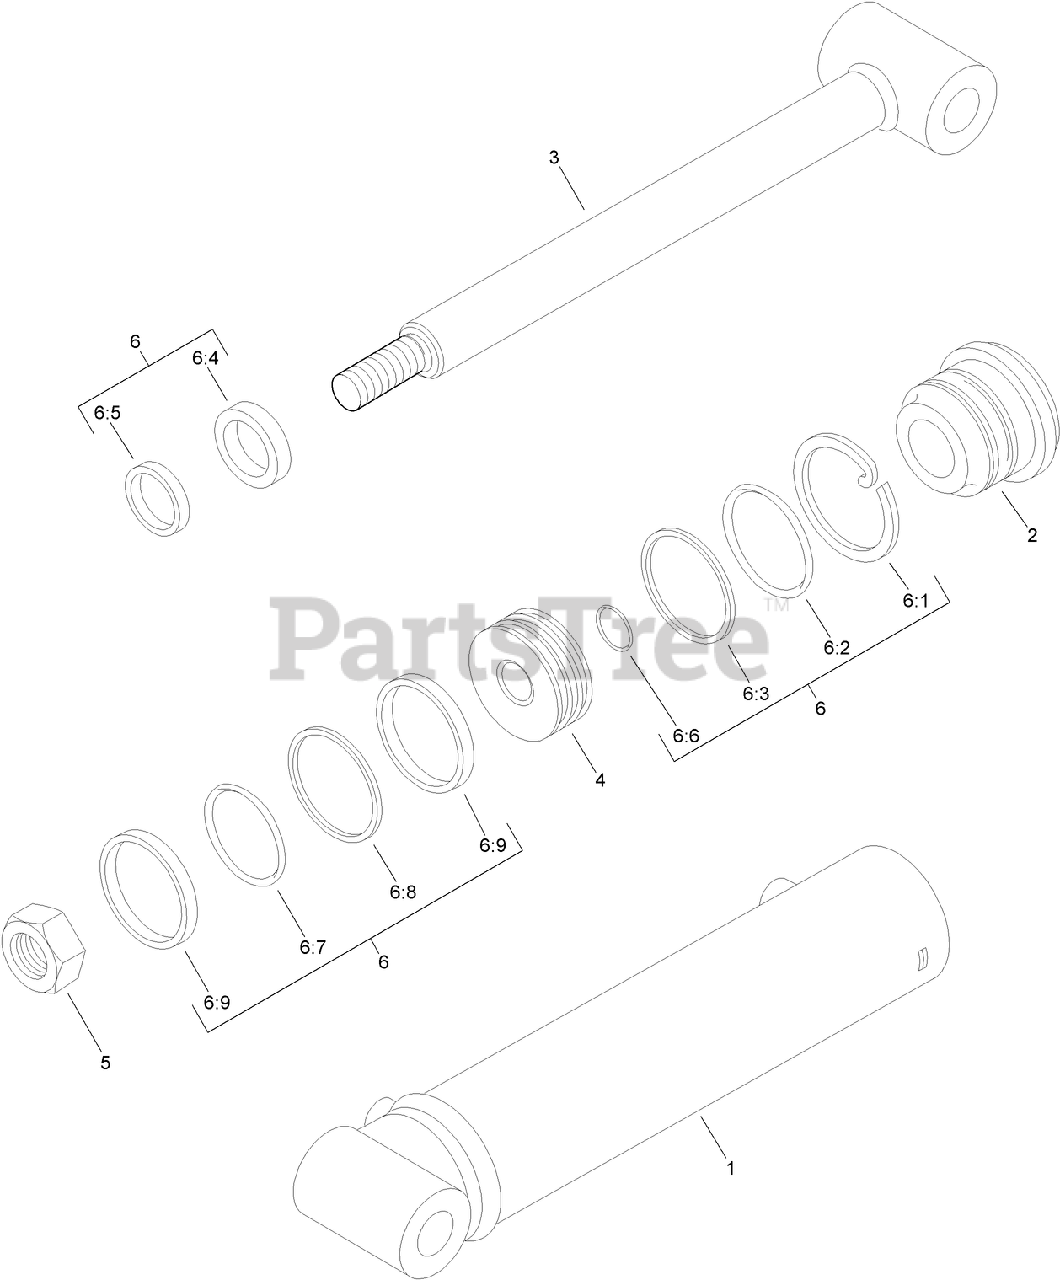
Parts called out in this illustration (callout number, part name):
1	CASE ASM
3	ROD-piston
5	NUT-LOCK
6	SEAL KIT
6:1	WIRE-locking, gland
6:2	O-RING, GLAND
6:3	Ring-Back Up
6:4	WIPER-piston rod
6:5	Seal-U Cup
6:6	O-RING, PISTON ROD
6:7	O-RING, PISTON
6:8	Ring-Back Up
6:9	RING-wear, piston
